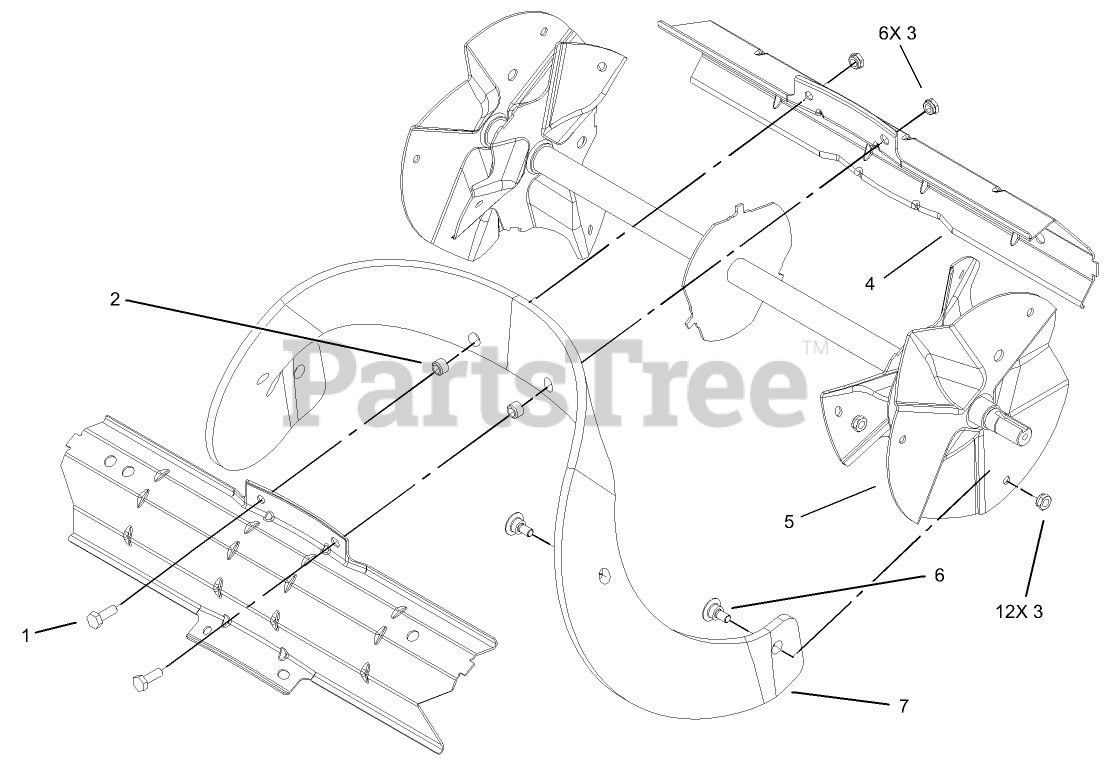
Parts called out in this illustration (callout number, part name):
1	SCREW-HH
2	SPACER-BLADE, ROTOR
3	NUT-LOCK, NI
4	DRUM-ROTOR
5	ROTOR ASM
6	SCREW
7	BLADE-ROTOR
